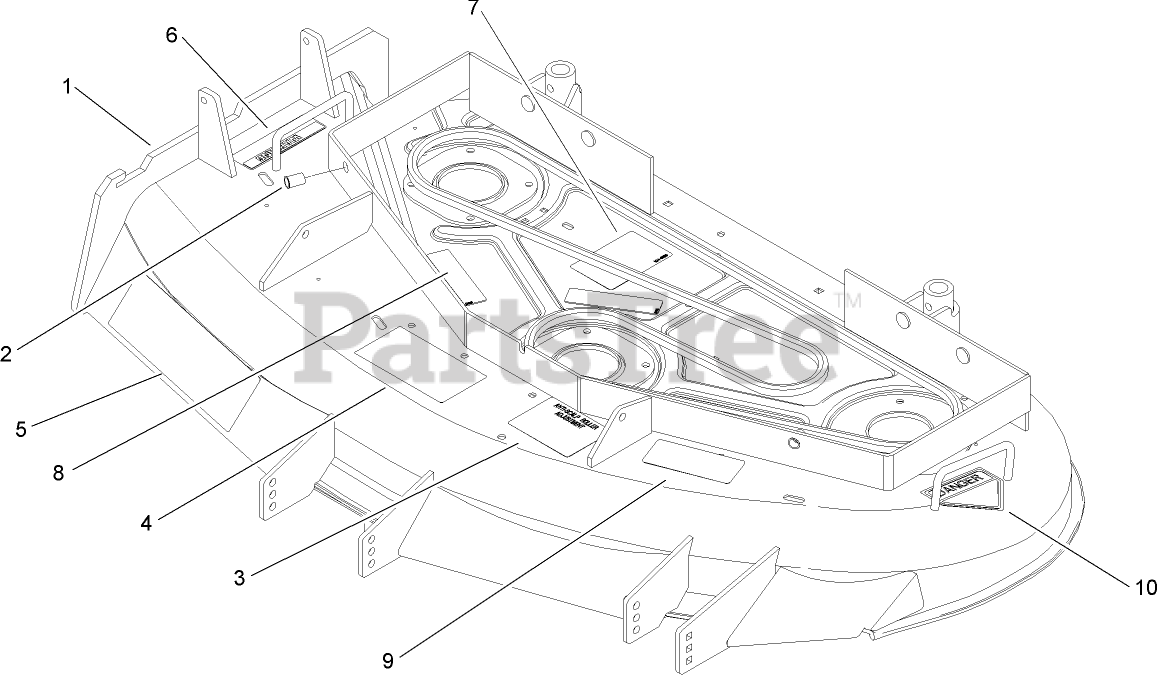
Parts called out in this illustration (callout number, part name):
1	44IN DECK ASM
2	INSERT-NUT
3	DECAL-ANTI SCALP
4	DECAL-DANGER, THROWN OBJECT
6	DECAL-WARNING
7	DECAL-ROUTING, BELT
8	DECAL-DANGER
9	DECAL-TORQUE
10	DECAL-DANGER
